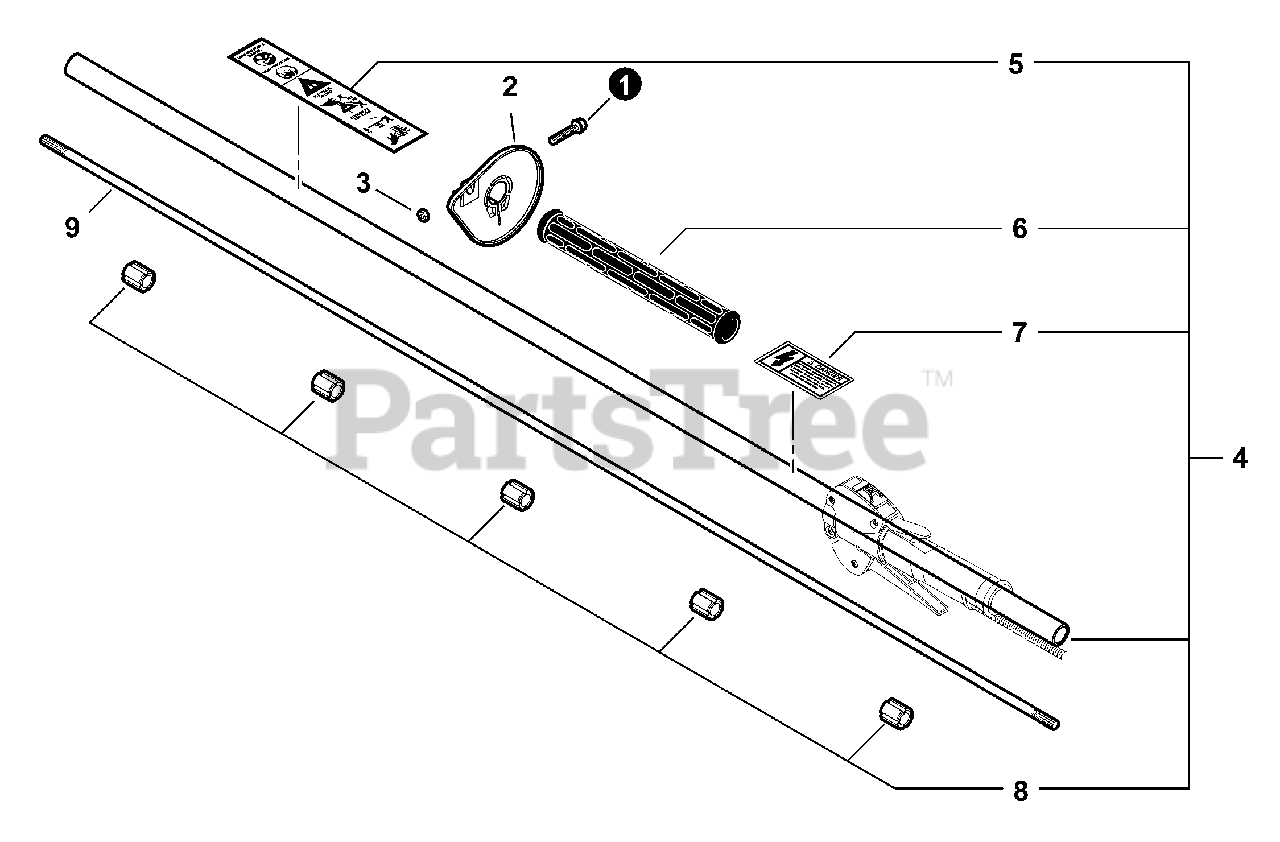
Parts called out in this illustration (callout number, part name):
1	SCREW M5×30
2	GUARD, HAND
3	NUT M5
4	MAIN PIPE ASSY WITH GRIP
5	LABEL, CAUTION
6	GRIP, FRONT
7	LABEL, HIGH VOLTAGE
8	BUSHING
9	MAINSHAFT
